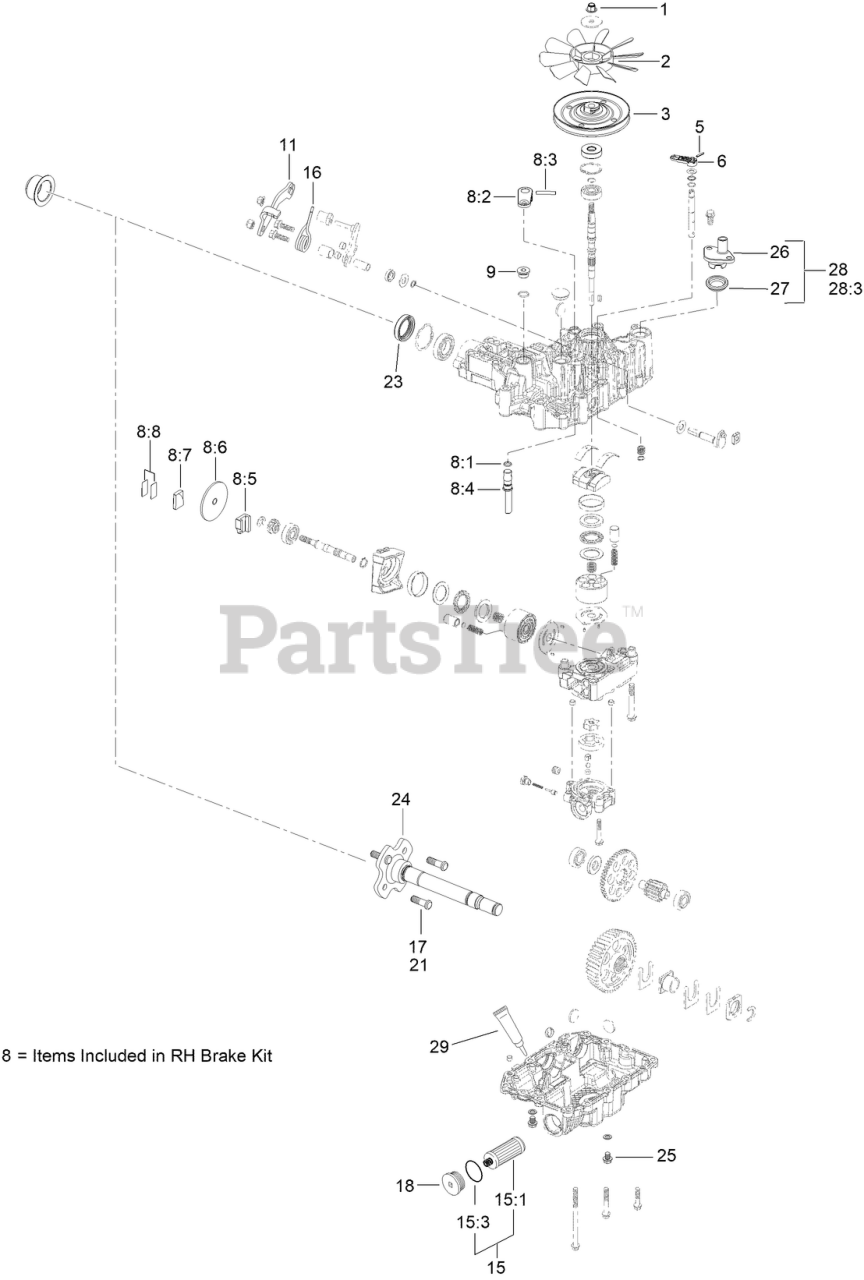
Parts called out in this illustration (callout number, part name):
1	NUT-LOCK
3	PULLEY
6	LEVER-BYPASS
8	BRAKE KIT,LEFT
8:1	O-RING
8:2	BRAKE ARM
8:3	Roll Pin
8:4	BRAKE SHAFT
8:5	BRAKE ACTUATOR
8:6	Brake Disc
8:7	BRAKE SHOE
8:8	SHIM KIT
9	CAP-OIL
11	LEVER-CONTROL, RH
15	2 TRANSMISSION FILTER KIT
15:3	SEALING WASHER
16	SPRING-TORSION
17	STUD-WHEEL
18	CAP-OIL FILTER
21	STUD-WHEEL
23	SEAL-AXLE, UA
25	DRAIN BOLT
26	EXPANSION FITTING
27	GROMMET SEAL, EXPANSION FITTING
28	EXPANSION FITTING - W/ SEAL
28:3	M8*20 FLANGE BOLT
29	SEAL KIT
